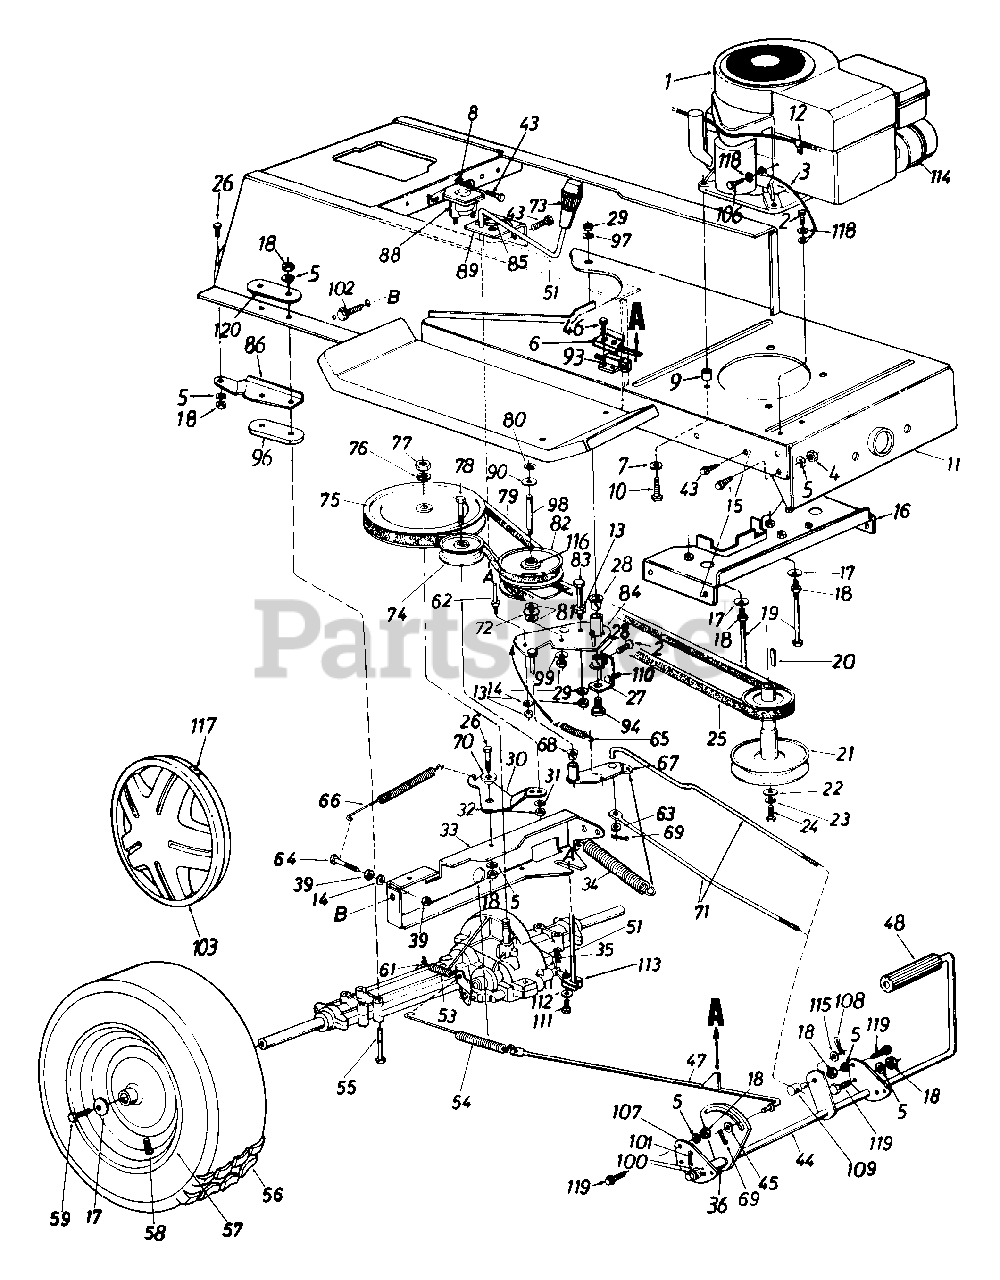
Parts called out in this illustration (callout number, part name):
1	Engine
2	Hex Wash. AB-Tap Scr. 5/16" x .75"
3	Electric Ground Wire
4	Hex Nut 5/16-24 Thd.
5	L-Wash. 5/16" I.D.
6	Switch Plate
7	Fl-Wash..406" I.D. x 1.25"
8	Ext. L-Wash. 1/4" I.D.
9	Spacer
10	Hex L-Wash. Tap Scr. 3/8-16 x 1.5" Lg. (B&S)
11	Lower Frame Ass'y.
12	Speed Clip
13	Hex Nut 1/4-20 Thd.
14	L-Wash. 1/4" I.D.
15	Rib Neck Bolt 5/16-24 x .84" Lg.
16	Belt Guard Brkt. Ass'y.
17	Bell-Wash..345" I.D. x.88"
18	Hex Nut 5/16-18 Thd.
19	Hex Bolt 5/16-18 x 4.0"
20	Sq. Key 1/4" x 1/4" x 2.00"
21	Engine Pulley
22	Fl-Wash. 7/16" I.D. x 1.25"
23	L-Wash. 7/16" I.D.
24	Hex Bolt 7/16-20 x 1.50" Lg.
25	Variable-Speed Belt
26	Hex Bolt 5/16-18 x .75" Lg.
27	Bearing Shaft Bracket Ass'y.
28	Flanged Nyliner Brg..63" I.D. x .6" Lg.
29	Hex Nut 3/8-24 Thd.
31	L-Wash. 3/8" I.D.
32	Hex Nut 3/8-24 Thd.
35	Inter. Cott-Pin
36	Spacer .63" I.D.
39	Hex Nut 1/4-28 Thd.
43	Hex Wash. Hd. S-Tap Scr. 1/4-20 x .50" Lg.
44	Clutch/Brake Pedal Ass'y.
45	Fl-Wash.
46	Truss Mach. Scr. B-Tap Scr. #10 x .5" Lg.
47	Brake Rod Ass'y.
48	Foot Pad
51	Shift Lever Ass'y.
53	Ext. Spring .38" O.D. x 2.5"
54	Ext. Spring 7.08"
55	Hex Bolt 5/16-18 x 3.5" Lg.
56	Wheel Ass'y. Comp.
57	Wheel Rim Only
58	Air Valve
59	Hex Bolt 5/16-24 x .75" Lg.
61	Brake Return Spring Anchor
62	Belt Guard Pin 1 4-20 Thd.
63	Fl-Wash..34" I.D. x.68" O.D.
64	Hex Bolt 1/4-28 x 1.25" Lg.
65	Ext. Spring
66	Ext. Spring .62" O.D. x 6.12"
69	Cotter Pin 3/32" Dia.
70	Shoulder Spacer .27" Lg.
71	Speed Control Link
72	Truss Bearing .56 Dia. x 1.25"
73	Shift Knob
74	Fl-)dier Pulley 3.25" x .75"
75	"V"-Pulley
76	Bell-Wash..56" I.D. x 1.125"
77	Hex Jam Nut 9/16-18 Thd.
78	Hex Bolt 3/8-24 x 1.75" Lg.
79	Variable Speed Belt
80	Snap Ring .56" Dia.
81	Fl-Wash.
82	Variable Speed Pulley Ass'y. 5" O.D.
83	Hex Bolt 1/4-20 x 3.5" Lg.
84	Variable Speed Brkt. Ass'y.
85	Comp. Spring - Clip
90	Teflon Washer .565" I.D.
93	Safety Switch (Clutch)
94	Shld. Bolt 3/8-24 x 3.12" Lg.
96	Transaxle Spacer
97	Bell-Wash..38" I.D. x .88"
98	Shaft .56" Dia. x 3.875" Lg.
99	Bell-Wash..39" I.D. x 1.12"
100	Fl-Wash..64" I.D. x .94"
101	Cotter Pin 1/8" Dia. x 1.25"
102	Hex Wash. Hd. Ger. 5/16-18 x .62" Lg.
103	Hub Cap (Gray)
106	Pan Hd. Mach. Scr. 5/16-18 x .75" Lg.
109	Ferrule
110	Hex Bolt 5/16-18 x 1.0" Lg.- (Gr. 5)
111	Hex Bolt 1/4-28 x .50" Lg.
112	Bell-Wash..265" I.D. x.75"
113	Shift Lever Link Ass'y.
114	Muffler
115	Fl-Wash..385" I.D. x .62"
116	Needle Brgs.
117	Spring Clip
118	External L-Wash. 5/16" I.D.
119	Hex Wash. TT-Tap Scr. 5/16-18 x .75"
